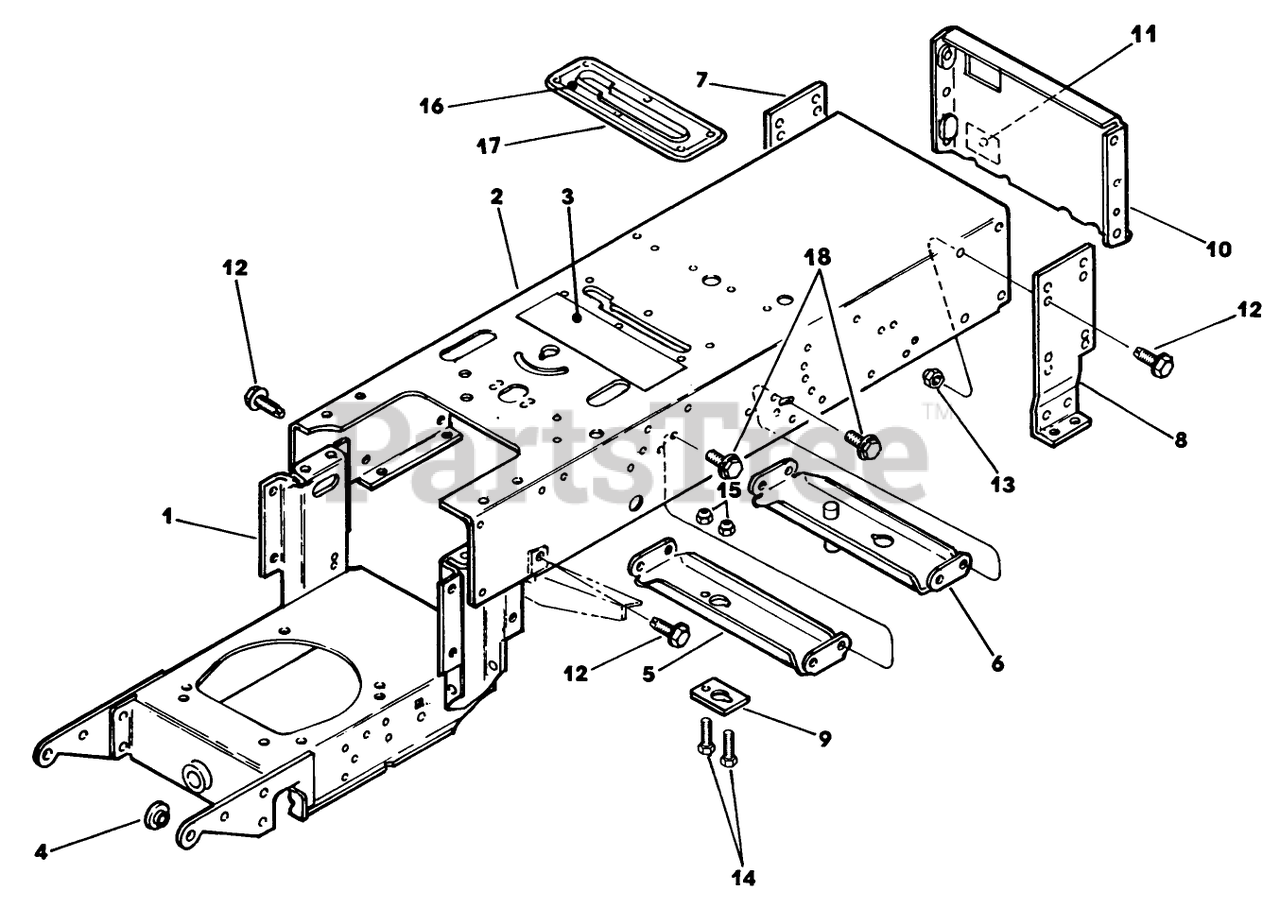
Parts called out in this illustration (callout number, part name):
2	FRAME & STICKER AY(12)
4	BEARING-NYLINER
5	SUPPORT *B
9	BRACKET-SUPPORT *B
13	NUT
14	SCREW
15	NUT-LOCK, CONE
